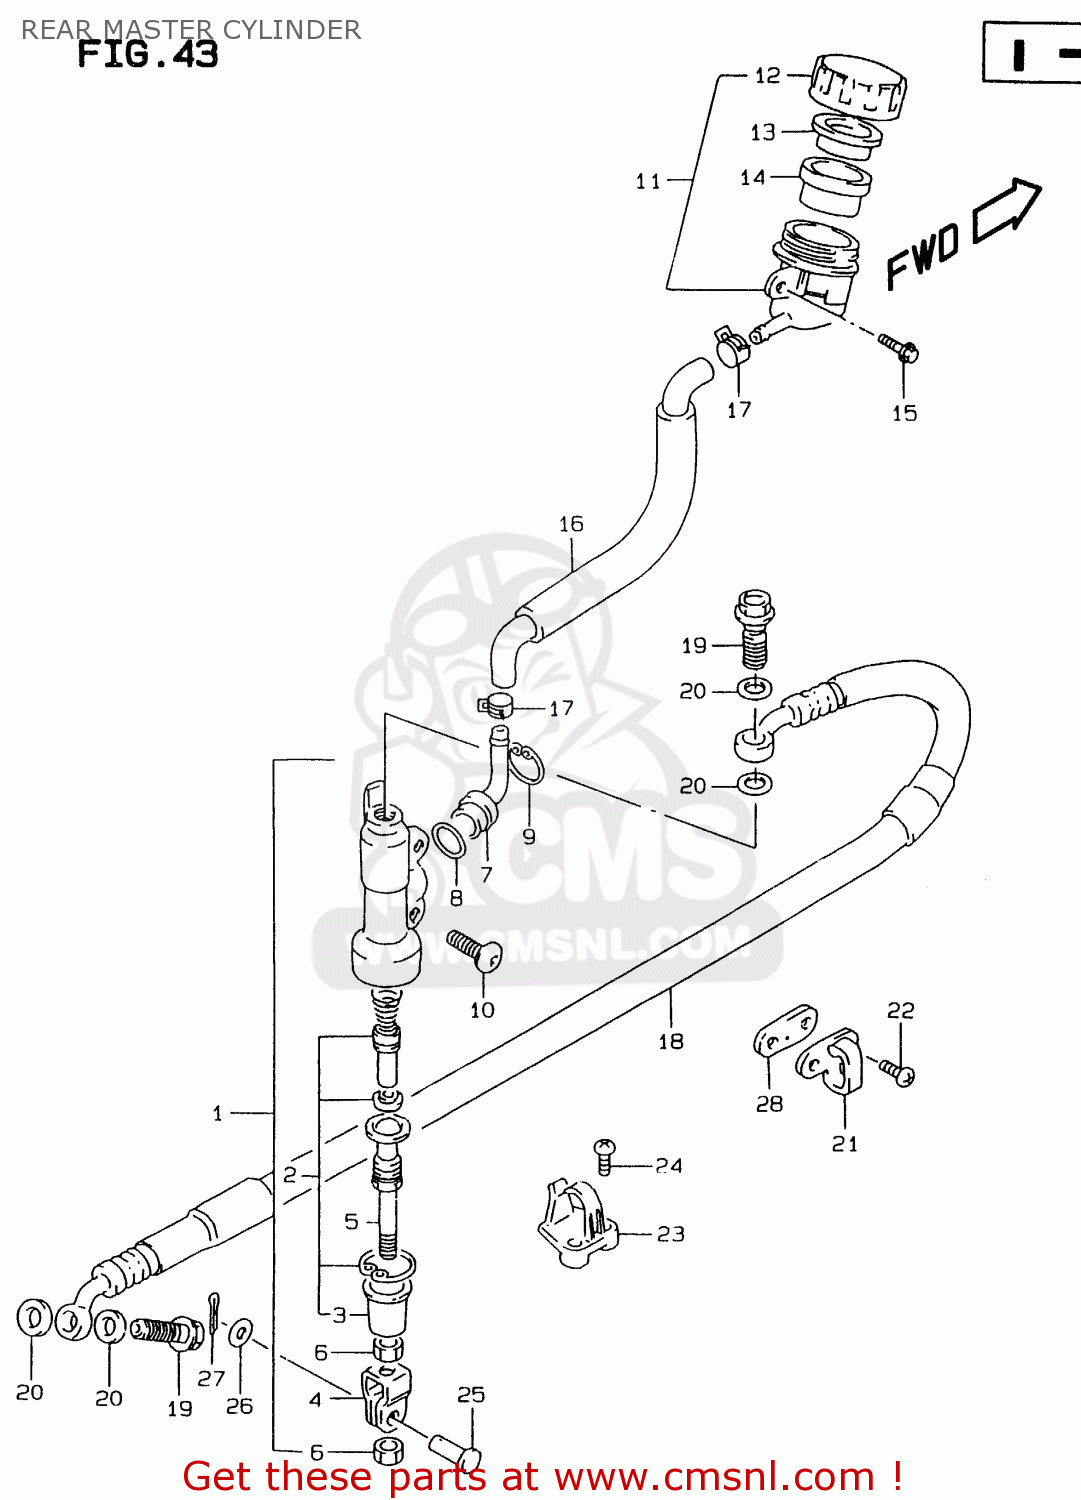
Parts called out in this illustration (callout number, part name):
1	CYLINDER ASSY,RR MASTER
2	PISTON/CUP SET
3	BOOT
4	YOKE
5	ROD,PUSH
6	NUT
7	CONNECTOR
8	O RING
9	CIRCLIP
10	SCREW(6X16)
11	TANK ASSY,RR BRAKE RESERVOIR
12	CAP
13	PLATE
14	DIAPHRAGM
15	BOLT
16	HOSE,TANK
17	CLAMP,RESERVOIR HOSE
18	HOSE,RR BRAKE
19	BOLT UNION
20	WASHER(10X15X1.5)
21	GUIDE,RR BRAKE HOSE
22	SCREW
23	GUIDE,RR BRAKE HOSE
24	SCREW
25	PIN(8X20)
26	WASHER(8.5X13X1.6)
27	PIN
28	SEAT,RR BRAKE HOSE GUIDE
